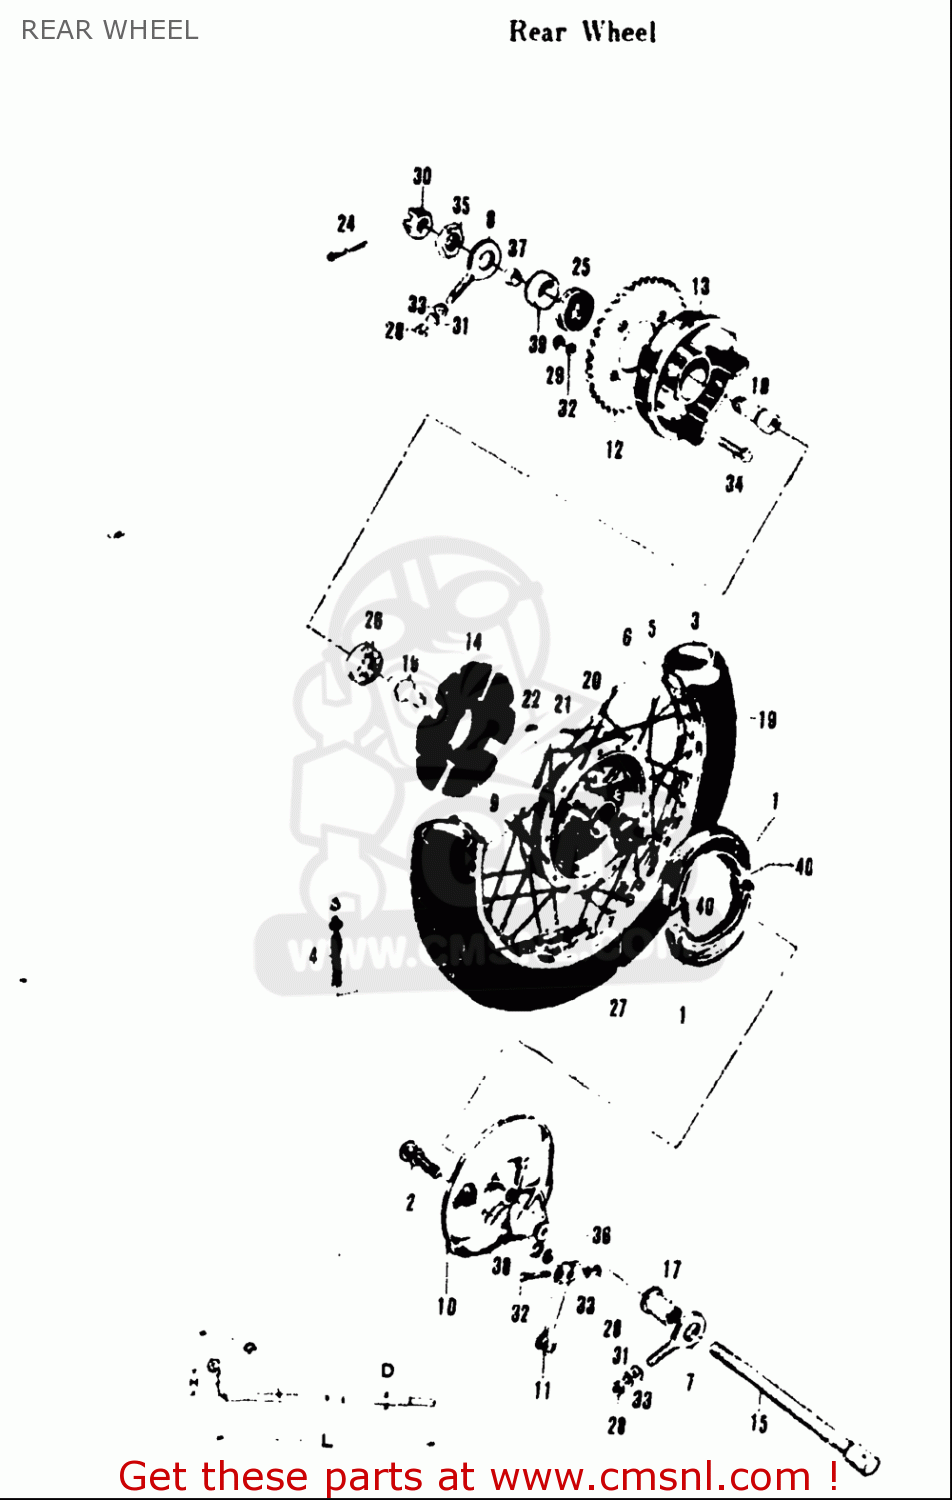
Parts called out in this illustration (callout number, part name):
5	PROTECTOR,WHL INR TUBE
6	RIM,WHEEL(1.40X17)
7	ADJUSTER,CHAIN,R
14	ABSORBER,RR WHEEL HUB SHOCK
18	SHAFT,RR SPROCKET DRUM
19	SPOKE SET,RR
25	BEARING(17X40X12)
26	BEARING
27	BEARING
28	NUT
29	NUT
30	NUT
31	WASHER,LOCK
32	WASHER,LOCK
33	WASHER
34	BOLT(8X33.5)
35	NUT
36	WASHER(12.5X20X1)
37	SPACER(17X25X10.5)
38	O RING(D:2.5,ID:11.4)
